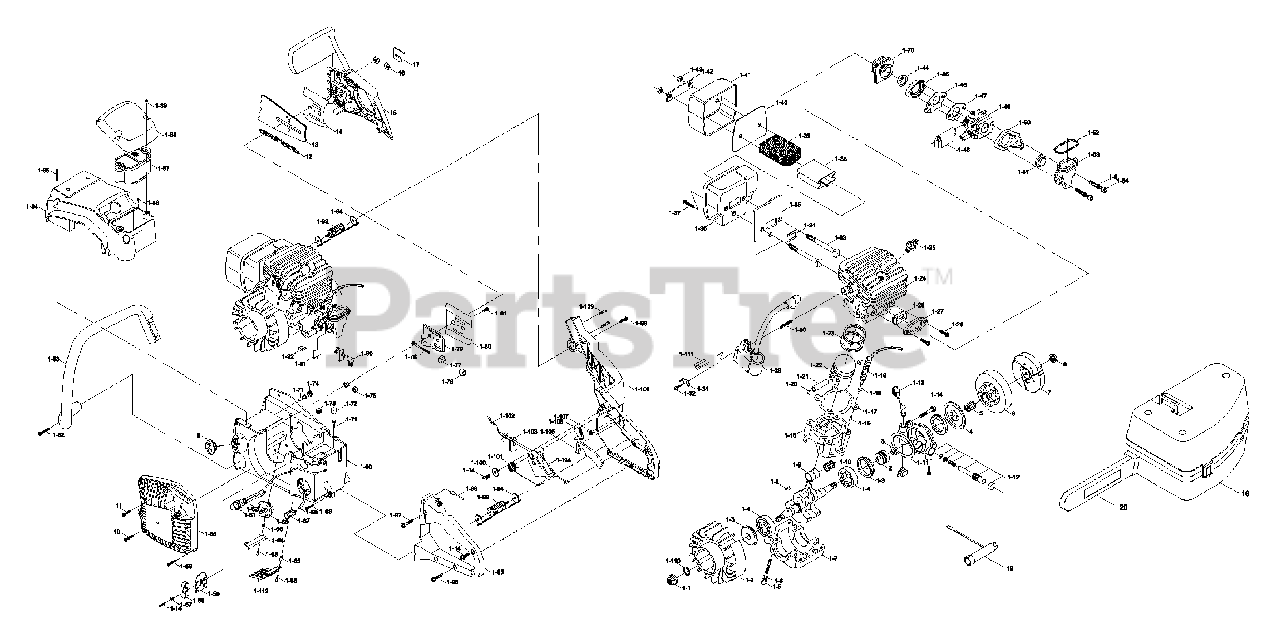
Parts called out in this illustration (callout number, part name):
1	POWERHEAD ASS'Y
1-7	CRANKCASE LOWER
1-9	C'SHAFT/C'ROD ASS'Y
1-12	PUMP ASS'Y
1-13	CONNECTOR
1-15	FITTING, PULSE LINE
1-16	CRANKCASE UPPER
1-18	CLAMP, WIRE HOSE
1-19	CONDUIT, FLEX
1-23	RING, PISTON
1-25	SPARK PLUG
1-29	IGNITION ASS'Y
1-31	CONTACT, CROUNT
1-36	MUFFLER BODY ASS'Y
1-41	COVER, MUFFLER
1-42	LOCKPLATE
1-55	STARTER ASS'Y
1-60	FUEL/OIL TANK ASS'Y
1-61	PRIMER, REMOTE
1-66	CAP, FUEL
1-67	FILTER, FUEL
1-70	BOOT, CARB
1-71	VALVE DUCKBILL
1-79	PLATE, BAR
1-80	PLATE, FLANGE
1-83	HANDLE ASS'Y
1-84	COVER ASS'Y
1-87	AIR CLEANER ASS'Y
1-90	CHOKE ASS'Y
1-91	ROD, CHOKE
1-93	ISOLATOR ASS'Y
1-94	CABLE ASS'Y
1-95	COVER ASS'Y, HANDLE
1-99	ISOLATOR ASS'Y
1-105	RELEASE. TRIGGER
1-106	LATCH, HIGH IDLE
1-108	FRAME, REAR
2	GEAR, WORM
6	DRUM SPRKT ASS'Y
7	CLUTCH ASS'Y
12	CHAIN (MS1846AVCC)
13	BAR
15	CHAIN BRAKE ASS'Y
19	CARRY CASE
